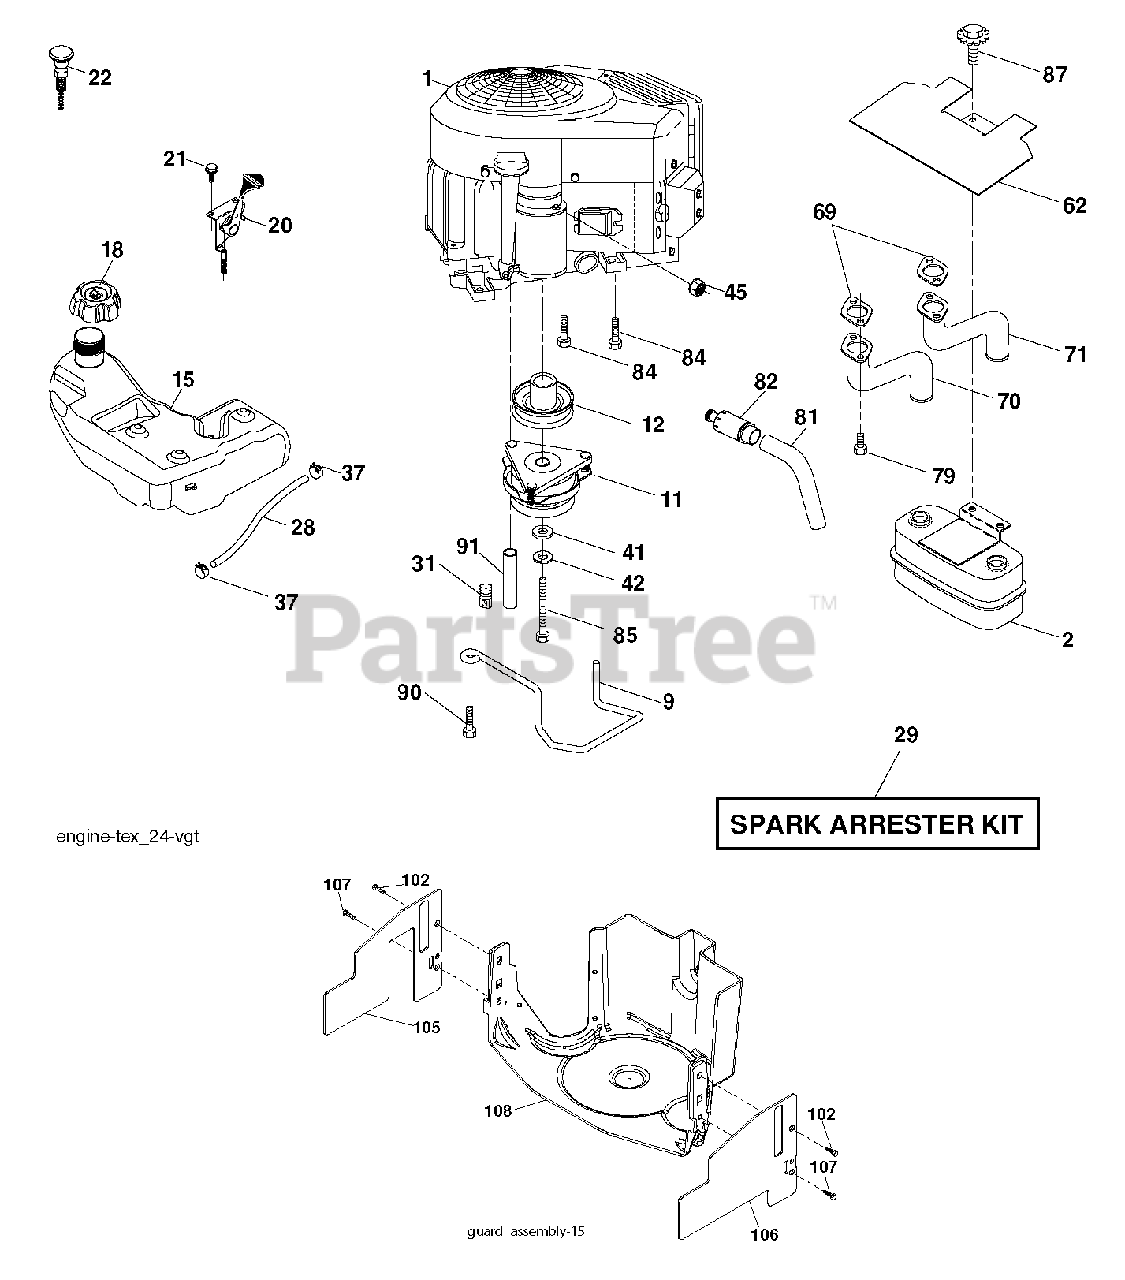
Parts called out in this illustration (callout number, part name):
2	MUFFLER.TWIN.CYL.LOW.TONE
9	KEEPER.BELT.ENGINE.4.2
11	CLUTCH
12	PULLEY.ENGINE.TUFFTORQ
15	TANK.FUEL.4GAL
18	CAP.ASM.FUEL.TANK.3"BL
20	THROTTLE CABLE
21	SCREW
22	CONTROL CHOKE
29	ARRESTER SPARK (OPTIONAL)
31	PUSH CLIP
37	HOSE CLAMP
42	LOCKWASHER
45	NUT
62	RP SHIELD HEAT MUFFLER
69	GASKET.MUFFLER
70	TUBE MANIFOLD LH
71	EXHAUST TUBE RH
79	SCREW.SOCKET.HEAD.5/16-18
81	TUBE, DRAIN OIL ASM.
82	PLUG DRAIN OIL EASY
84	SCREW.3/8-16
85	BOLT HEX 7/16-20X4-1/4"
87	BOLT.5/16-18UNCX1.W/SEMS.BLK
90	SCREW 3/8-16X1
91	BUSHING.1.375OD
102	SCREW
107	SCREW.1/4-20X5/8
